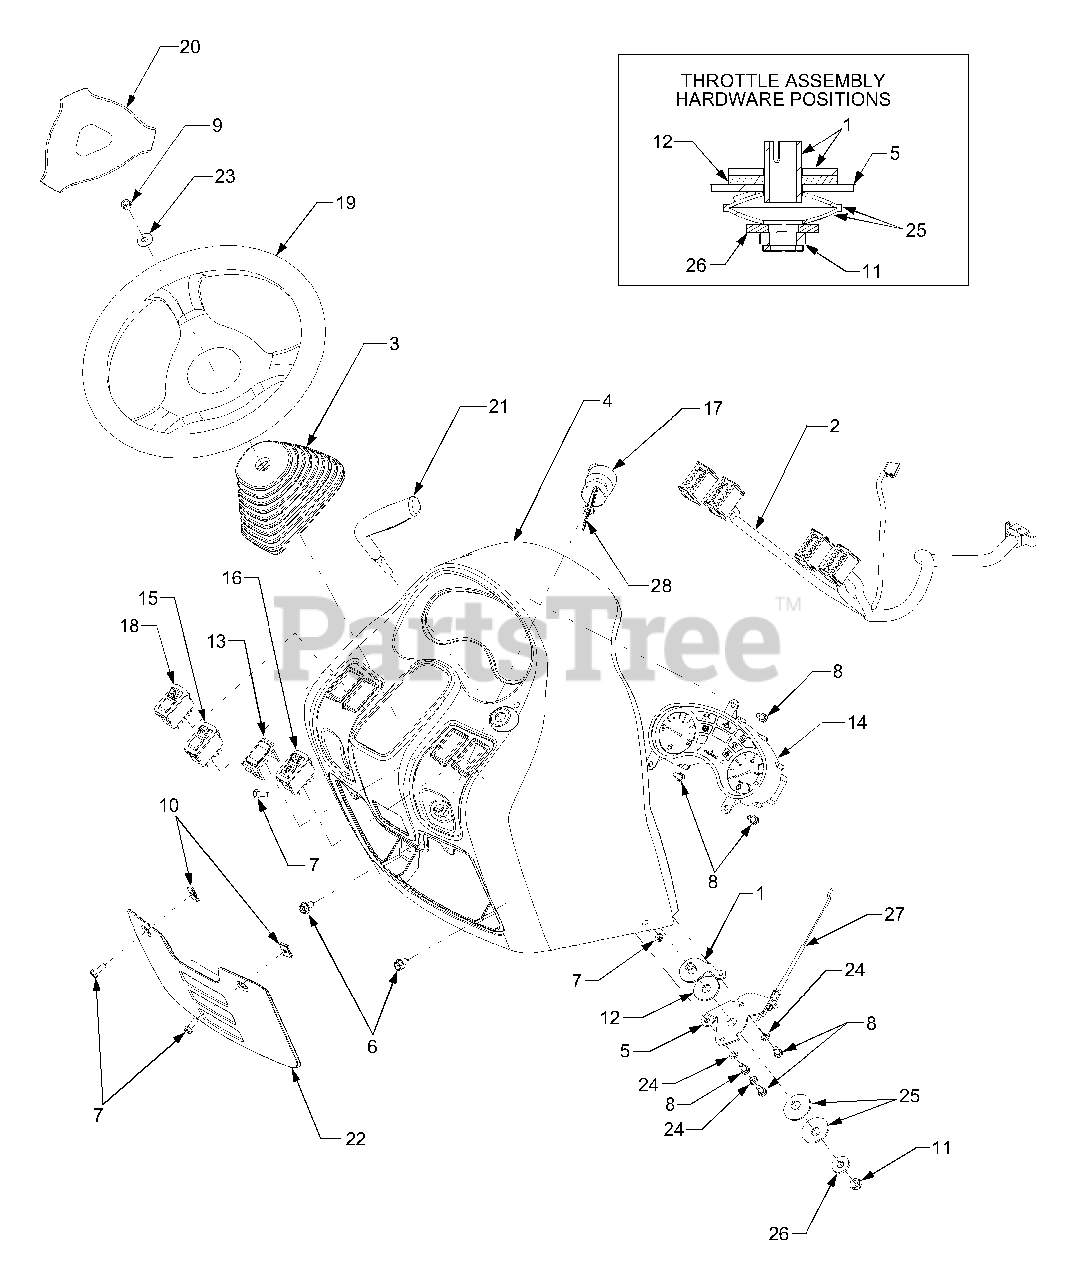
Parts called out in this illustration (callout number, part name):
3	Boot, Steering Shaft
4	Dash
5	Plate, Throttle Mtg.
6	Screw, Hex Wash. Hd. Tapp 5/16-18 x .625
7	Screw, Pan Hd., 1/4-20 x .75
8	Screw, Hex Cap, 1/4-20 x .5 GR5
9	Nut, Hex Lock, 5/16-24
10	Nut, Speed, 1/4-20
11	Nut, Hex Insert Jam Lock, 3/8-24
12	Washer, Friction, .515 x 1.5 x .12
14	Panel, Instrument
15	Switch, Headlight
16	Switch, PTO
17	Switch, Ignition
18	Switch, Hazard
19	Steering Wheel, Soft Grip
20	Cover, Steering Wheel
21	Handle, Throttle
22	Panel, Dash Insert
23	Washer, Belleville, .34 x .872 x .06
24	Washer, Lock, 1/4
25	Washer, Belleville, .531 x 1.62 x .045
26	Washer, Flat, .406 x 1.0 x .105
27	Cable, Throttle
28	Key Set, Ingition
